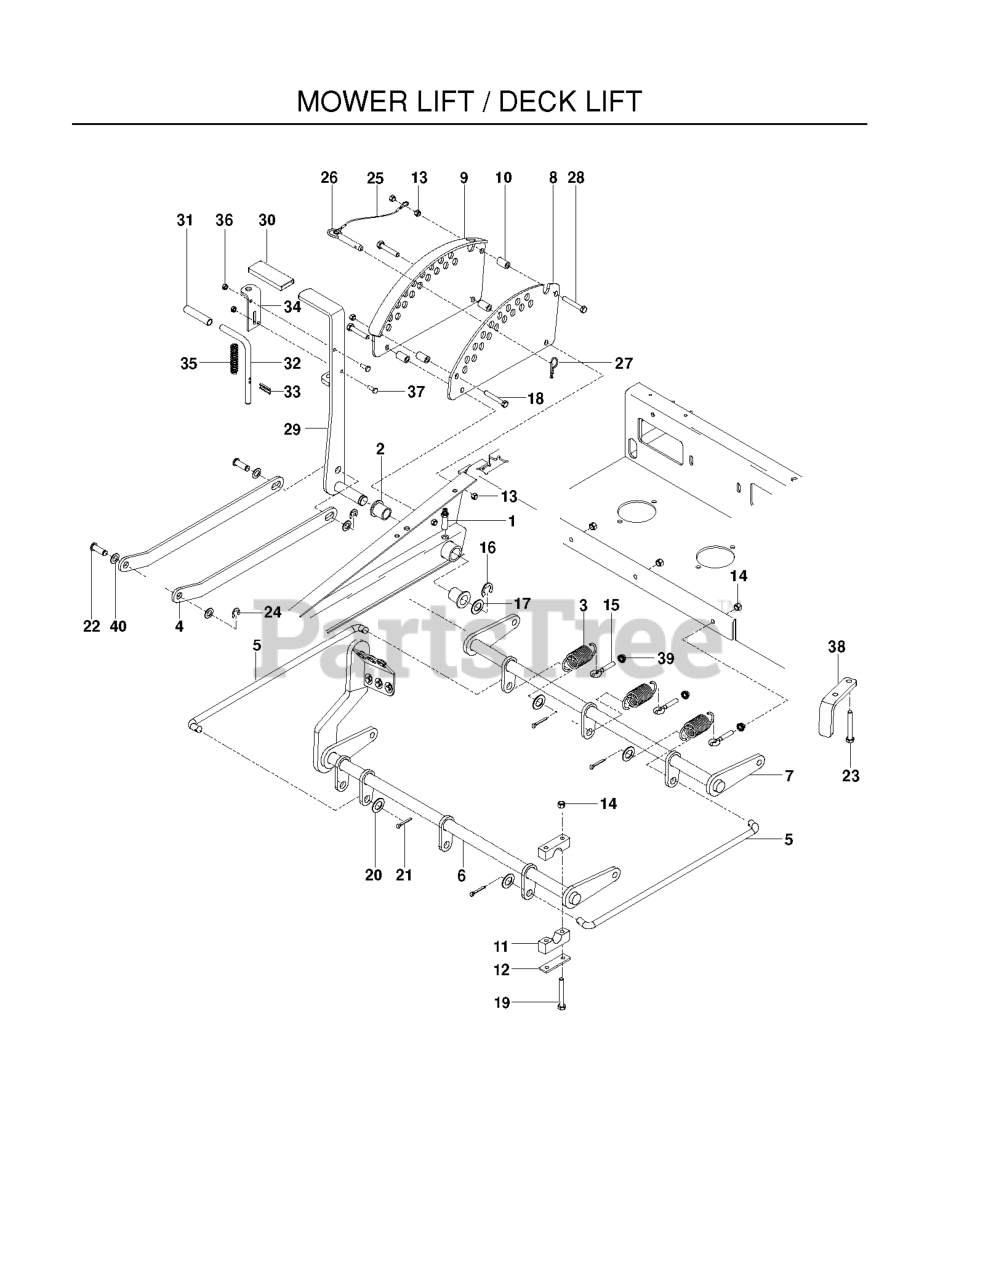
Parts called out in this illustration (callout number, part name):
1	GREASE ZERK LONG
2	BUSHING, FLANGED
3	DECK LIFT SPRING
4	LIFT LINKAGE,PAINTED
5	CONNECTING LINK
6	LIFT SHAFT ASM, FRONT
7	SHAFT LIFT REAR
8	ADJ. PLATE PAINTED
9	ADJ. PLATE WLDMNT
10	DECK LIFT SPACER
11	PILLOW BLOCK
12	REINFORCEMENT BAR
13	NUT 3/8-16 NYLOC
14	5/16-18 NYLOC FLANGE NUT
15	EYEBOLT, RH
16	E-RING 7/8
17	BSHG .875 X 1.375 X .074 ZD
18	HCS 3/8C X 2 1/2
19	HCS 5/16C X 2-3/4
20	WASHER 5/8 FLAT
21	COTTER PIN
22	CLEVIS PIN
23	BOLT 3/8-16 X 1.0
24	E-RING 5/8
27	HAIRPIN #4
28	SCREW 3/8C X 2 3/4 HEX CAP
29	LIFT LEVER WELDMENT
34	PIN MT, UPPER
36	NUT 1/4C CENTER LOCK
37	HCS 1/4C X 3/4 HCS
39	NUT 5/16C WHIZ
